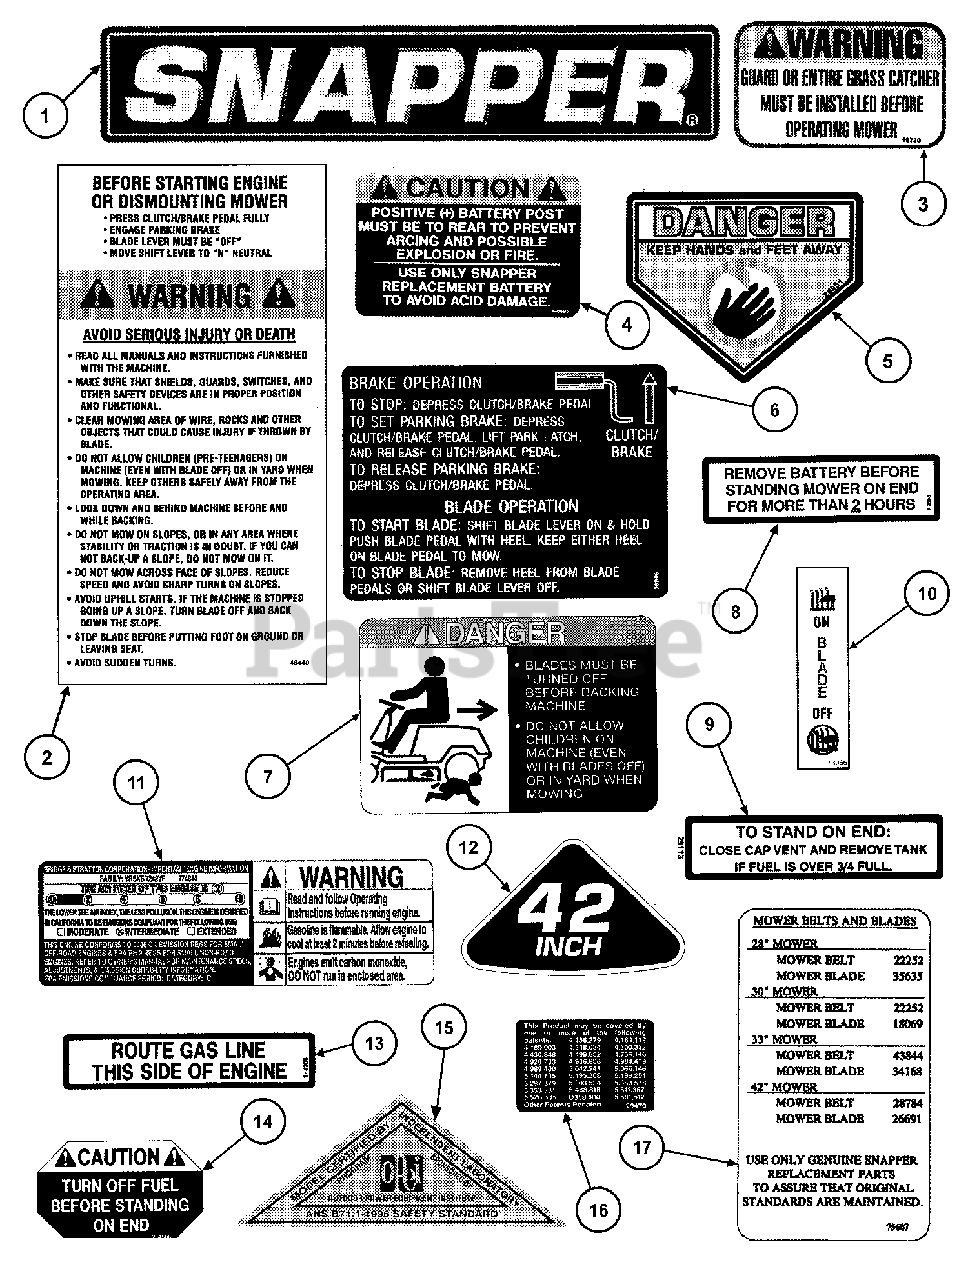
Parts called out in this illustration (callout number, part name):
1	DECAL, SNAPPER
2	DECAL, Warning, Safety Instructions
3	DECAL, Chute/Deflector
4	DECAL, Battery Caution
5	DECAL, Danger (Heavy Adhesive)
6	DECAL, Brake/Blade Operation
7	DECAL, No-Mow-In-Reverse
8	DECAL, Battery
9	DECAL, Caution, Fuel (English)
10	DECAL, Blade Engagement, 42"
11	DECAL, B&S AIR Index/Emission Label
12	DECAL - 42 Inch
13	DECAL, Fuel Routing
14	DECAL, Fuel Shut-Off
15	DECAL OPEI Ride-On
16	DECAL, Patent Numbers
17	DECAL, Service Parts, RER Domestic
